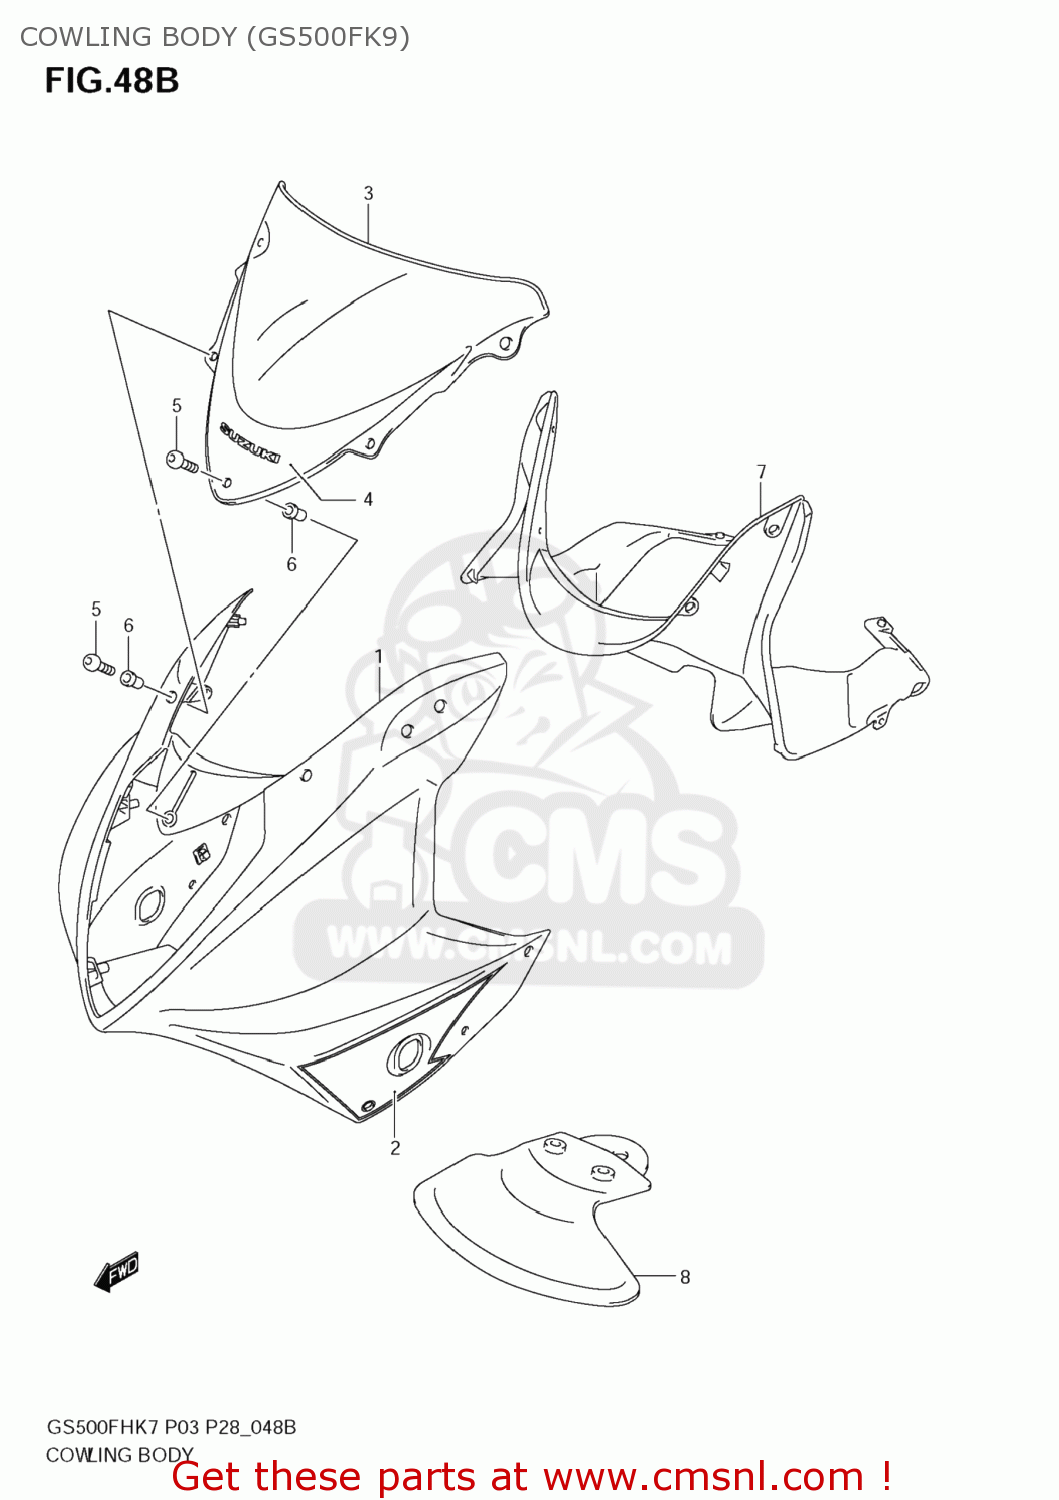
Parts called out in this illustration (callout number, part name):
1	BODY,COWLING G
2	TAPE SET,COWLIN
3	WINDSCREEN
4	TAPE,WINDSCREEN
5	SCREW(5X18)
6	NUT
7	PANEL GS500F
8	COVER,LOWER BRA
